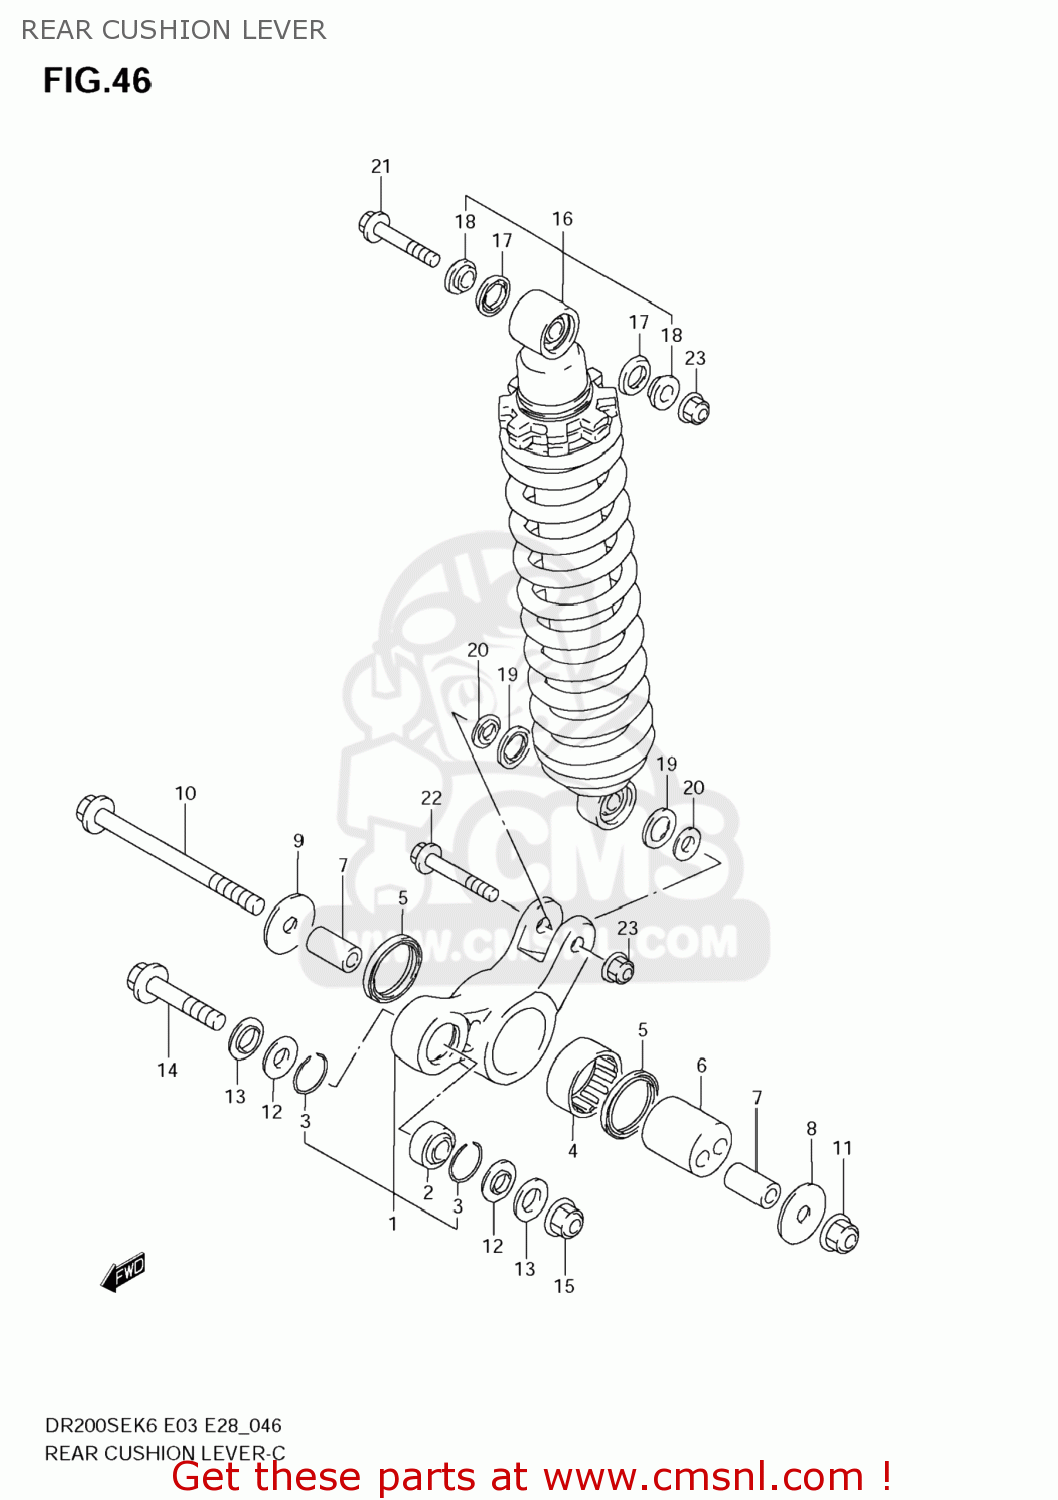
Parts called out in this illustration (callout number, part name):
1	LEVER SET,RR CUSHION
2	BEARING(12X26X16)
3	RING,BEARING STOPPER
4	BEARING(37X47X20)
5	SEAL,DUST
6	SPACER,RR SUSPENSION ECCENTRIC
7	SPACER,CUSHION LEVER SHAFT
8	WASHER,RR CUSH LVR CTR,L
9	WASHER,RR CUSH LVR CTR,R
10	SHAFT,RR CUSHION LEVER CTR
11	NUT
12	SEAL,RR CUSHION ROD DUST
13	SPACER,RR CUSHION ROD
14	BOLT,CUSHION LEVER FR
15	NUT
16	ABSORBER ASSY,RR SHOCK
17	DUST SEAL
18	SPACER
19	DUST SEAL,RR SHOCK
20	COLLAR
21	BOLT(10X58)
22	BOLT(10X48)
23	NUT
